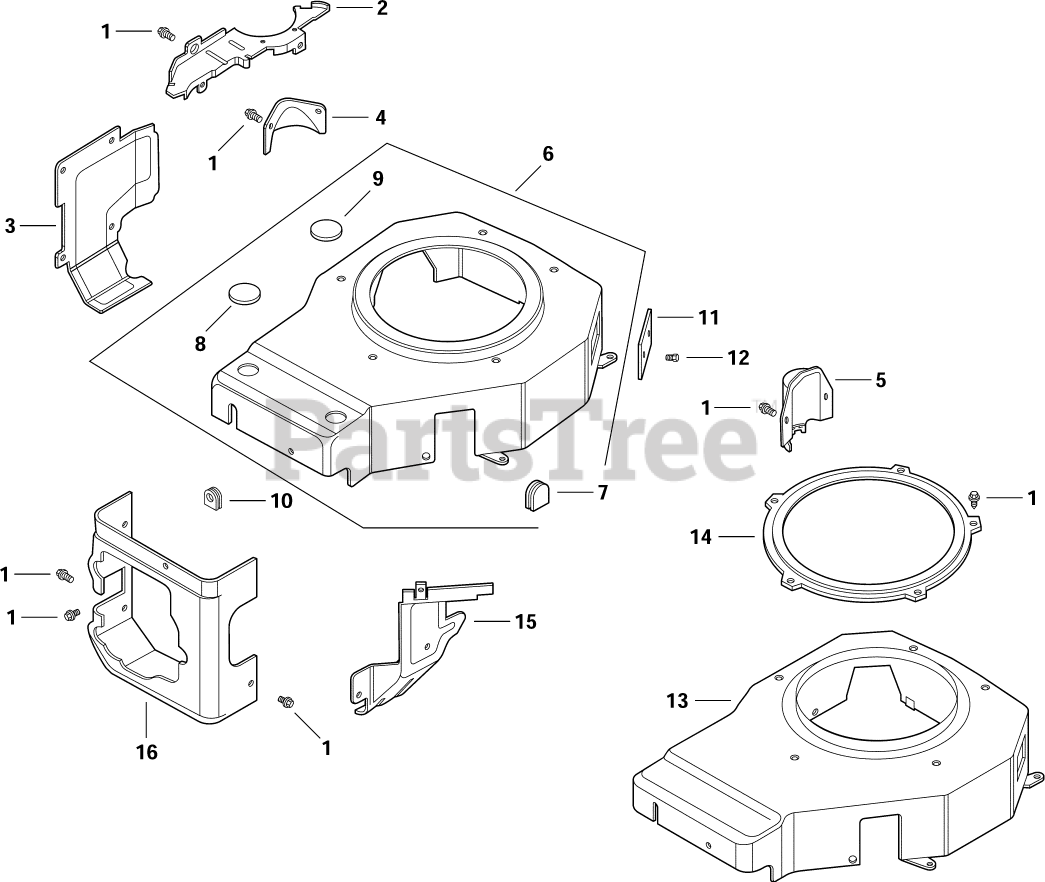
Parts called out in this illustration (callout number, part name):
1	SCREW, FLG THD FRM M5X.8X10
2	PLATE, BACKING
3	BAFFLE, CYLINDER
4	COVER, STARTER MOTOR
13	KIT, BLOWER HOUSING
15	BAFFLE, INTAKE SIDE
16	BAFFLE, CYLINDER HEAD
